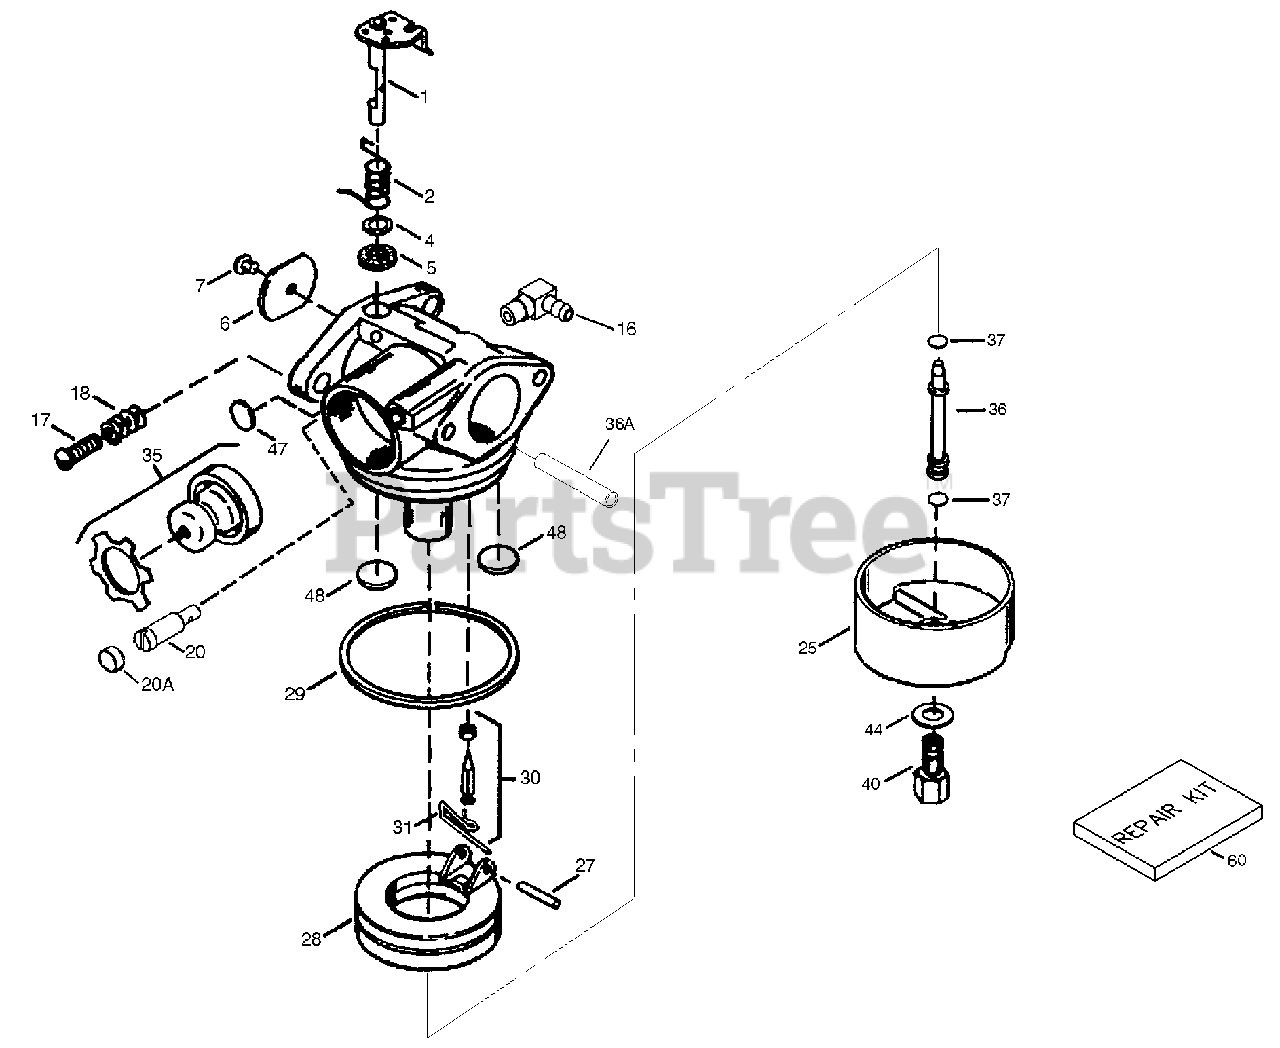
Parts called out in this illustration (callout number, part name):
1	Throttle Shaft & LeverAssembly
2	Throttle Return Spring
4	Dust Seal Washer
5	Dust Seal (Throttle)
6	Throttle Shutter
7	Shutter Screw
16	Fuel Fitting
17	Throttle Crack
18	Tension Spring
20	Idle Restrictor Screw
20A	Idle Restrictor Screw
25	Float Bowl
27	Float Shaft
28	Float (Plastic)
29	Float Bowl "O" Ring
30	Inlet Needle, Seat,& Clip (Incl. 31)
31	Spring Clip
35	Primer Bulb/RetainerRing
36	Main Nozzle Tube
36A	Bowl Vent Tube
37	O-Ring, Main NozzleTube
40	High Speed Bowl Nut
44	Bowl Nut Washer
47	Welch Plug, Idle
48	Welch Plug,Atmospheric Vent
60	Repair Kit
61	Carburetor To IntakePipe Gasket
